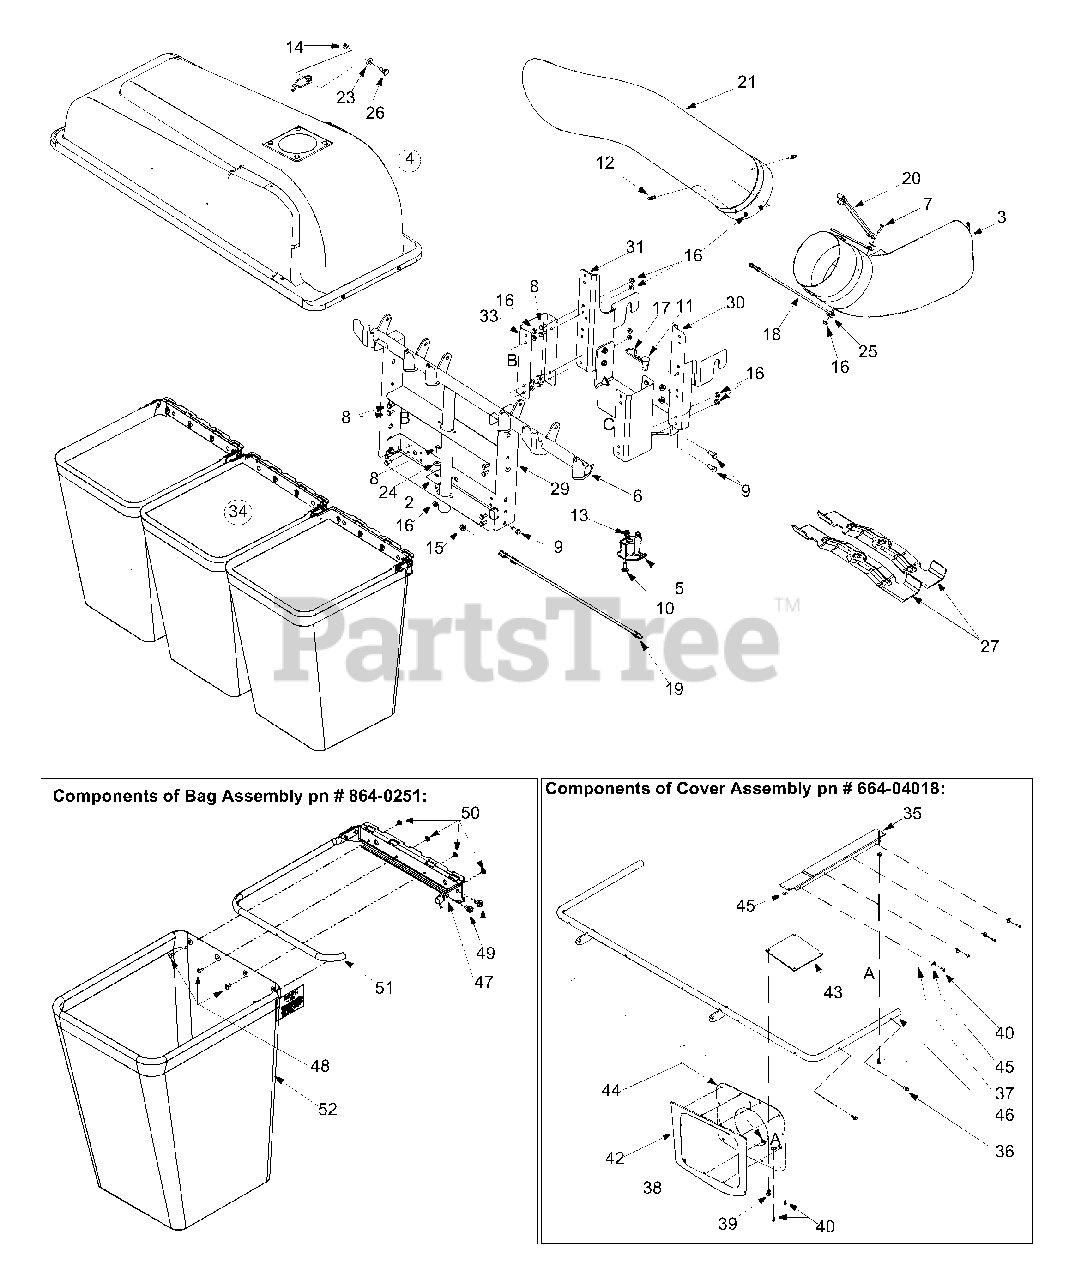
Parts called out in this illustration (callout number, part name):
1	Catcher Support Bracket
3	Chute Elbow
4	Cover Assembly
6	Grasscatcher Support Assembly
7	Hex Bolt 1/4-20 x 1.0
8	Hex Bolt 1/4-20 x 0.620
9	Hex Bolt 5/16-18 x 0.75
10	Carriage Bolt
11	Clevis Pin
12	Grasscatcher Pin
13	Hex Lock Nut 3/8-16
14	Flange Lock Nut 3/8-16
15	Flange Lock Nut 5/16-18
16	Flange Lock Nut 1/4-20
17	Hairpin Clip
18	Chute Strap
20	Chute Strap
21	Catcher Tube
23	Beleville Washer
24	Bell Washer
25	Flat Washer
26	Shoulder Screw
27	Blade
37	Screen
38	Push Nut
39	Ratchet Clip
40	Pop Rivet
41	Grass Bag Cover
42	Retainer Seal
43	Plastic Plate
44	Grass Bag Seal
45	Flat Washer
46	Hinge Bracket
48	Machine Screw
49	TT Screw 5/16-18 x 0.625
50	Hex Sems Nut
